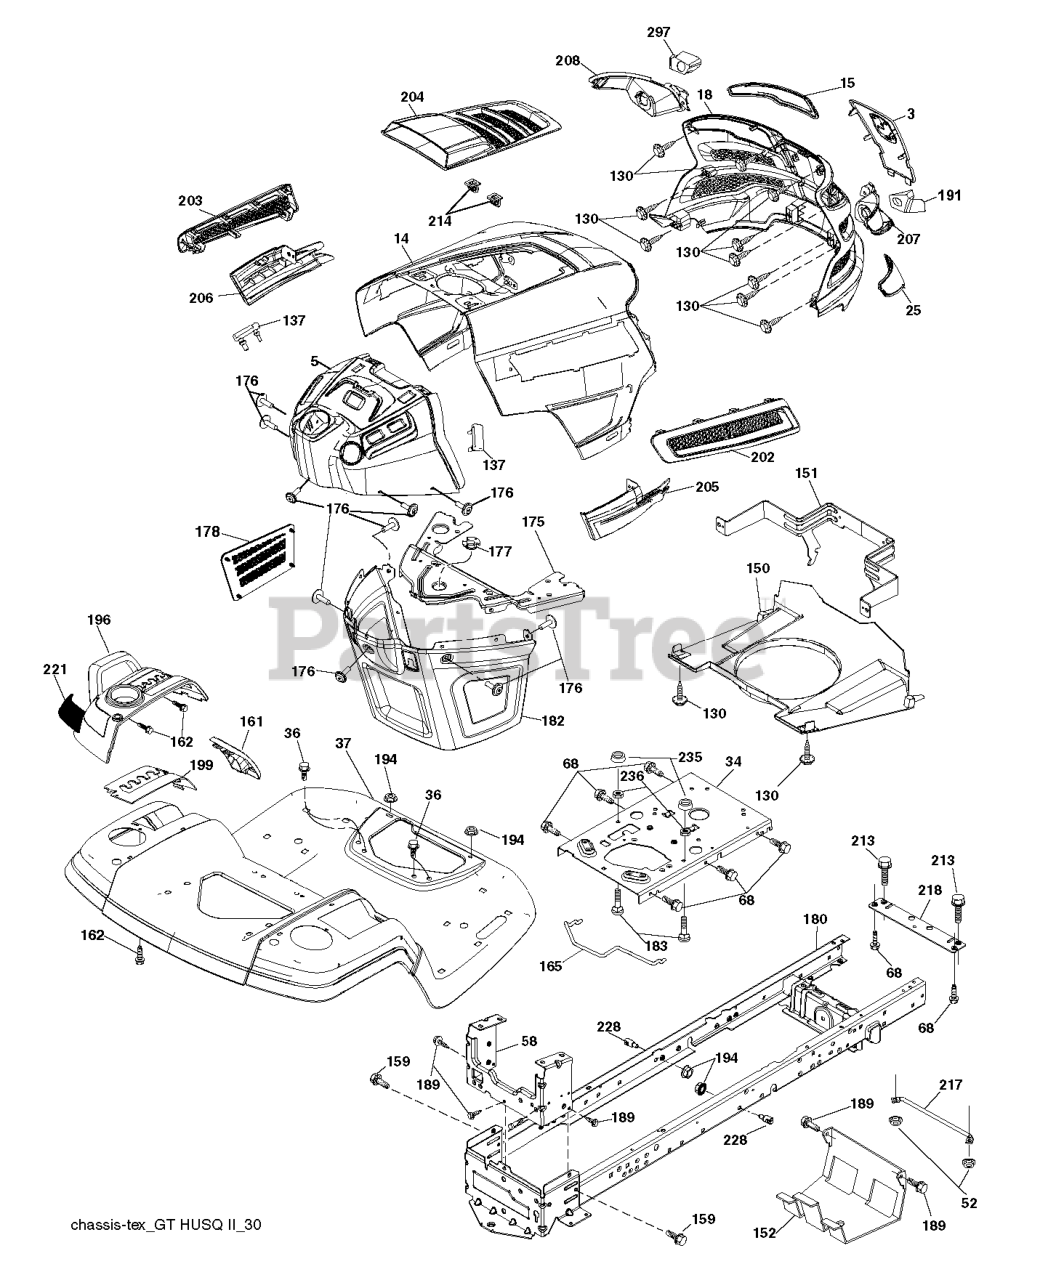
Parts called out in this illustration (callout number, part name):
3	APPLIQUE.SUBASM.GT.HUSQ.II
5	DASH.UPPER.GT2.SM.PTO.M/CH.GRE
14	HOOD.ASM.HUSQVARNA.GT.TEX.ORAN
15	LENS.HEADLIGHT.LH.GTII.2011
18	GRILLE.SUBASM.GT.HUSQ.II
25	LENS.HEADLIGHT.RH.GTII.2011
34	PLATE.ENGINE.WELDED.CHASSIS
36	SCREW 5/16"
37	FENDER.PNT.TX.GT.CH/FW/DL.HUSQ
52	LOCKNUT
58	DRAWBAR.UPPER.2PC,LRG.FENDER
68	Screw 5/16-18 x 1/2 Hex, Self Tapping 5/16-18 x 1/2
130	SCREW.#10 X 0.750.BOS
137	BUMPER DASH
150	AIR.DUCT.GTV.BLACK
151	BRACKET.PIVOT.HOOD.GT.HUSQ.II
152	SHIELD.BROWNING.W/TEX
159	SCREW, 3/8-16X3/4
161	CONSOLE.WINDOW.FUEL.HUSQ.GT
162	SCREW.HI-LO.CONSOLE
165	SUPPORT.TANK.REAR.W/TEX
175	PLATE.CROSSMEMBER.HUSQ
176	SCREW.#10-24X5/8.RN.QU
177	BUSHING, STEERING
178	CARGO.ASM.NET.TXGT.W/C
180	CHASS.WLDMNT.TLT.12GA/2PC.20"
182	DASH.LOWER.COMMON.12V.ADAPTOR
183	BOLT.5/16-18X1-1/4 FULL THD
189	SCREW
191	INSERT.REFLECTIVE.RH.HUSQ.GTII
194	NUT LOCK HEX FLANGE 5/16-18
196	SUBASM.CONSOLE.HUSQ.GT.DECKLFT
199	PLATE.DECK.LIFT.HUSQVARNA.GT
202	VENT.SIDE.RH.GT.HUSQ.II.
203	VENT.SIDE.LH.GT.HUSQ.II.498
204	VENT.TOP.HUSQ.GT2
205	SIDE.TRIM.RH.GT.HUSQ.II
206	SIDE.TRIM.LH.GT.HUSQ.II.GRAY
207	BEZEL LIGHT.RH.GT.II.MYLAR
208	BEZEL LIGHT.LH.GT.II.MYLAR
213	BOLT
214	CLIP.RETAINER.TINNER.
217	ROD.PIVOT.HOOD
218	X-PIECE.HOOD.STOP.NON/
221	REFLECTOR.LH.TEX GT HU
228	STUD.FASTNER.W/ANTI-ROTATE
235	SPACER FENDER
236	NUT.CENTERLOCK.5/16-
297	INSERT.REFLECTIVE.LH.HUSQ.GTII
